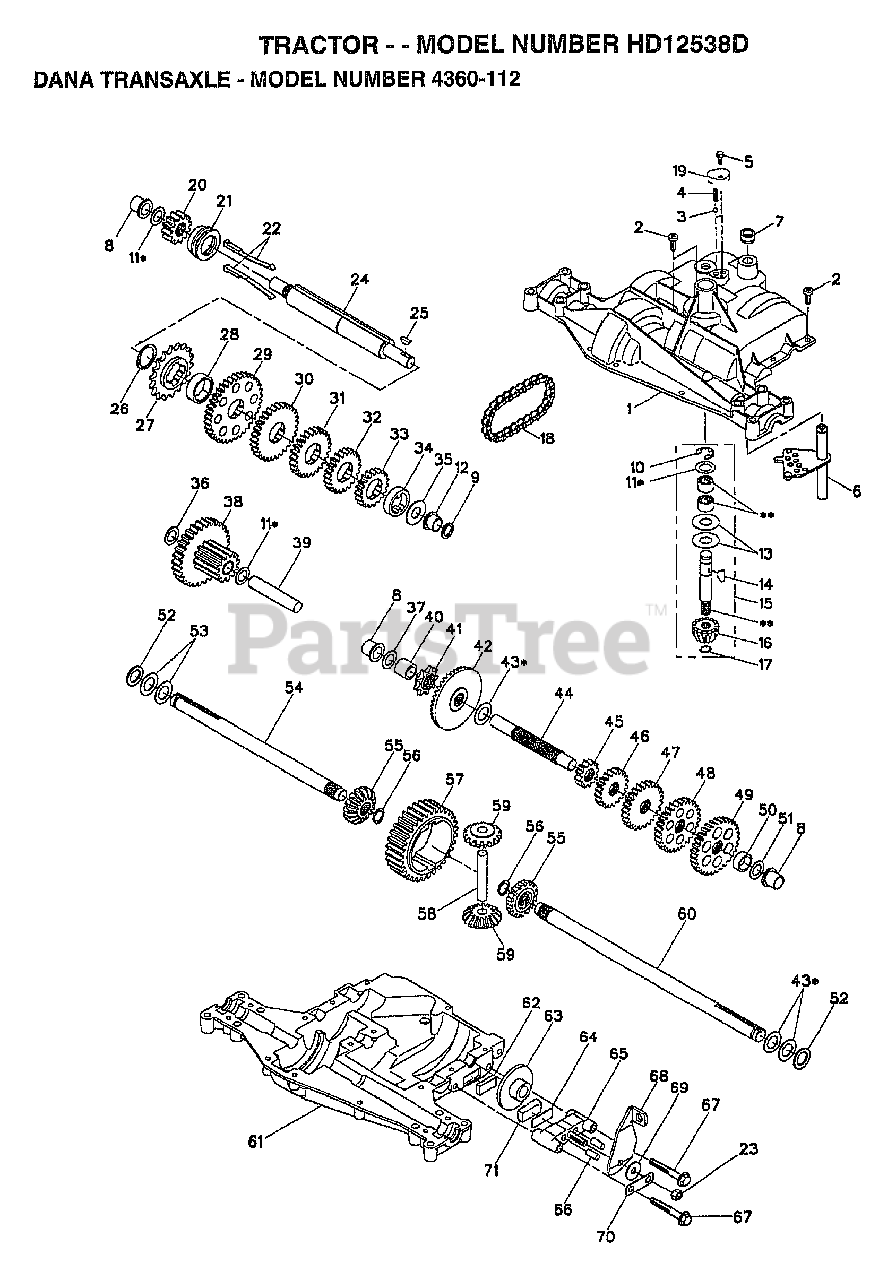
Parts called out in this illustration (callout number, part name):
1	HOUSING, UPPER
3	BALL, DETENT
4	SPRING, DETENT
5	SCREW, #10-24 X .482
6	SHIFTER ASSEMBLY
8	BEARING, FLANGE
10	RING, RETAINING
11	ASSY, KIT, SHIM .625 SHAFT
12	BEARING, FLANGE
13	WASHER, PLAIN .632 X 1.38 X .046
14	KEY, WOODRUFF, #9
15	ASSEMBLY, KIT, INPUT SHAFT
16	PINION, BEVEL, 14 TEETH
17	RING, RETAINING
18	CHAIN, 24 PITCHES
19	COVER, DETENT
20	GEAR, SPUR, 12T
21	COLLAR, CLUTCH
22	ASSEMBLY, KIT, CLUTCH KEYS
23	LOCKNUT 5/16-24
24	SHAFT, INTERMEDIATE
25	KEY, WOODRUFF, #61
26	RING, RETAINING
27	SPROCKET, 18 TEETH
29	GEAR, SPUR, 37 TEETH
30	GEAR, SPUR, 30 TEETH
31	GEAR, SPUR, 25 TEETH
32	GEAR, SPUR, 22 TEETH
33	GEAR, SPUR, 19 TEETH
35	WASHER, PLAIN .640 X 1.37 X .061
36	WASHER PLAIN
37	WASHER PLAIN
38	ASSY, GEAR COMB 12T & 30T
39	SHAFT, IDLER
40	SPACER .635 X .875 X .755
41	SPROCKET, 9 TEETH
42	GEAR, BEVEL, 42 TEETH
43	ASSY, KIT, SHIM .750 SHAFT
44	SHAFT, DRIVE
45	GEAR SPUR, 12 TEETH
46	GEAR, SPUR, 20 TEETH
47	GEAR, SPUR, 25 TEETH
48	GEAR, SPUR, 28 TEETH
49	GEAR, SPUR, 31 TEETH
51	WASHER, PLAIN .632 X 1.00 X .060
52	WASHER, NEOPRENE
53	WASHER, PLAIN .758 X 1.25 X .031
55	GEAR, MITER, 15 TEETH
56	RING, RETAINING
57	GEAR, SPUR, 32 TEETH
58	SHAFT, CROSS
59	GEAR, MITER, 15 TEETH
61	HOUSING, LOWER
62	PUCK, FRICTION
63	DISC, BRAKE
65	JAW, BRAKE
66	PIN, DOWEL
67	SCREW, 5/16-18 X 2.35
68	LEVER ACTUATING
69	WASHER, PLAIN .321 X 1.00 X .055
70	BRACKET, ANTI-ROTATION
71	PUCK, FRICTION
